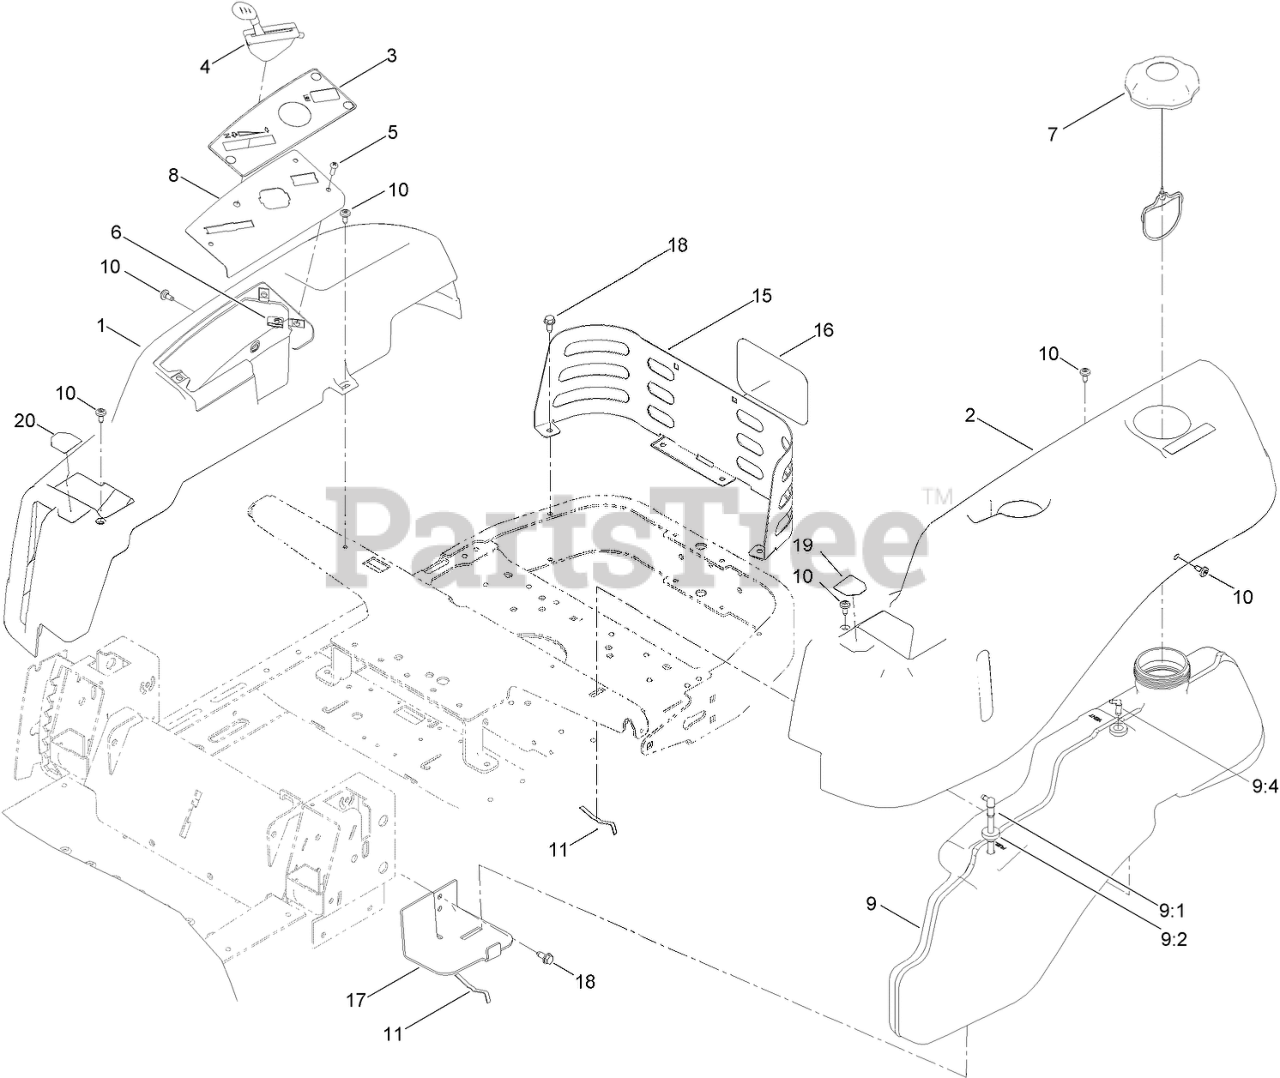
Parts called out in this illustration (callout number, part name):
1	POD-RH
2	POD-LH
3	DECAL-PANEL, CONTROL
4	CABLE-THROTTLE AND CHOKE
5	SCREW-PRH
7	CAP-FUEL, RATCHETING
8	PLATE-CONTROL
9	FUEL TANK ASM
9:1	CONNECTOR-ELBOW, 90 DEG
9:2	BUSHING
9:4	FITTING-PLASTIC
10	SCREW-SHOULDER
11	SPRING
15	GUARD-REAR
17	SUPPORT-TANK, FRONT
18	SCREW-HWHTF
19	DECAL-CONTROL LEVER, LH
20	DECAL-CONTROL LEVER, RH
